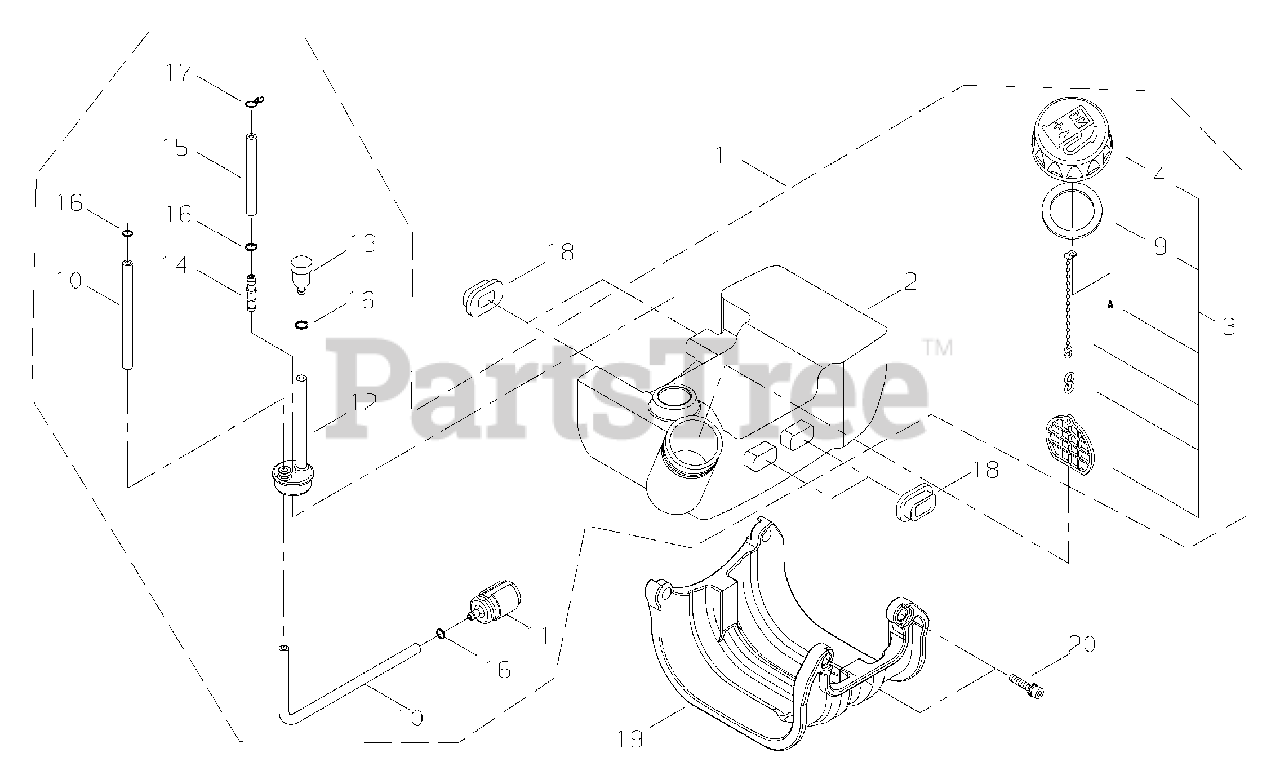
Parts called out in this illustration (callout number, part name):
1	TANK ASSY, FUEL
2	TANK, FUEL
3	CAP ASSY, FUEL
4	CAP, FUEL
9	GASKET, FUEL CAP
10	PIPE, FUEL
11	FILTER, FUEL 125-528
12	GROMMET, FUEL W/VENT PIPE
13	VENT ASSY
14	CONNECTOR, PIPE
15	PIPE, FUEL RETURN
16	CLIP Ø6
17	CLIP, SPRING Ø5.2
18	CUSHION, FUEL TANK
19	GUARD, PLASTIC FUEL TANK
20	BOLT M5×20
